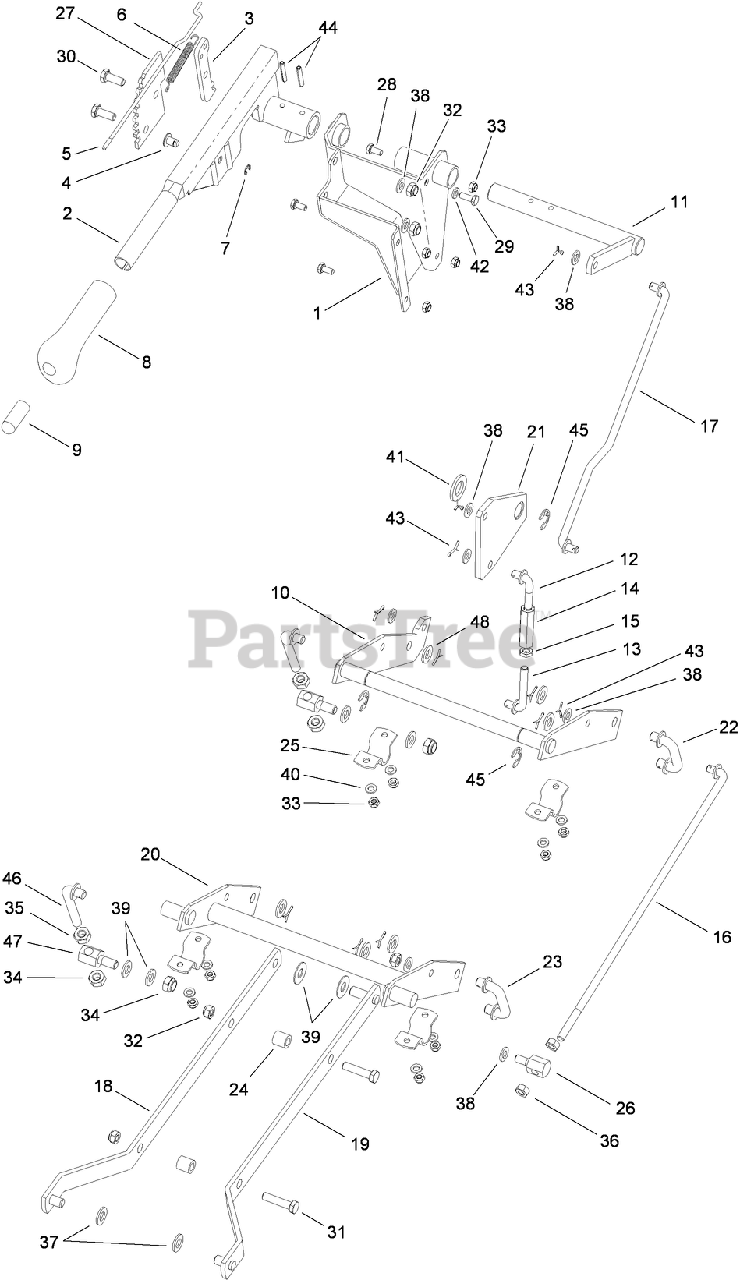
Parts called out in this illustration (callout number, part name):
1	BRACKET
2	LEVER ARM
3	RATCHET-PLATE, PIVOT
4	PIN-LEVER, ARM
5	ROD-CONNECTION
6	SPRING
7	CLIP-PIN
8	GRIP-HANDLE
9	BUTTON-PLUNGER
10	HANGER-REAR
11	SHAFT-ADJUSTMENT, HEIGHT
12	ROD-TOP
13	ROD-LOWER
14	NUT-TURNBUCKLE
15	NUT-HEX
16	ROD-LINKAGE
17	ROD-LINKAGE
18	BRACKET-RIGHT DECK SUPPORT
19	BRACKET-LEFT DECK SUPPORT
20	HANGER-FRONT
21	BRACKET-LINKAGE
22	DECK LINK, U-SHAPE, 50
23	DECK LINK, U-SHAPE, 55
24	SPACER
26	TRUNNION
27	GEAR-SECTOR
28	SCREW-HH
29	SCREW-HH
30	SCREW-HH
31	SCREW-HH
32	NUT-LOCK, NI
33	NUT-LOCK
34	NUT-LOCK, NI
36	NUT-HEX
37	Washer
38	WASHER-PLAIN
39	WASHER-FLAT
40	WASHER
41	WASHER-FLAT
42	WASHER-SPRING
43	PIN-COTTER
44	PIN-SPRING
45	E-CLIP
46	LINK-DECK, L-SHAPE (ADJUSTABLE)
47	TRUNION
48	WASHER-PLAIN
